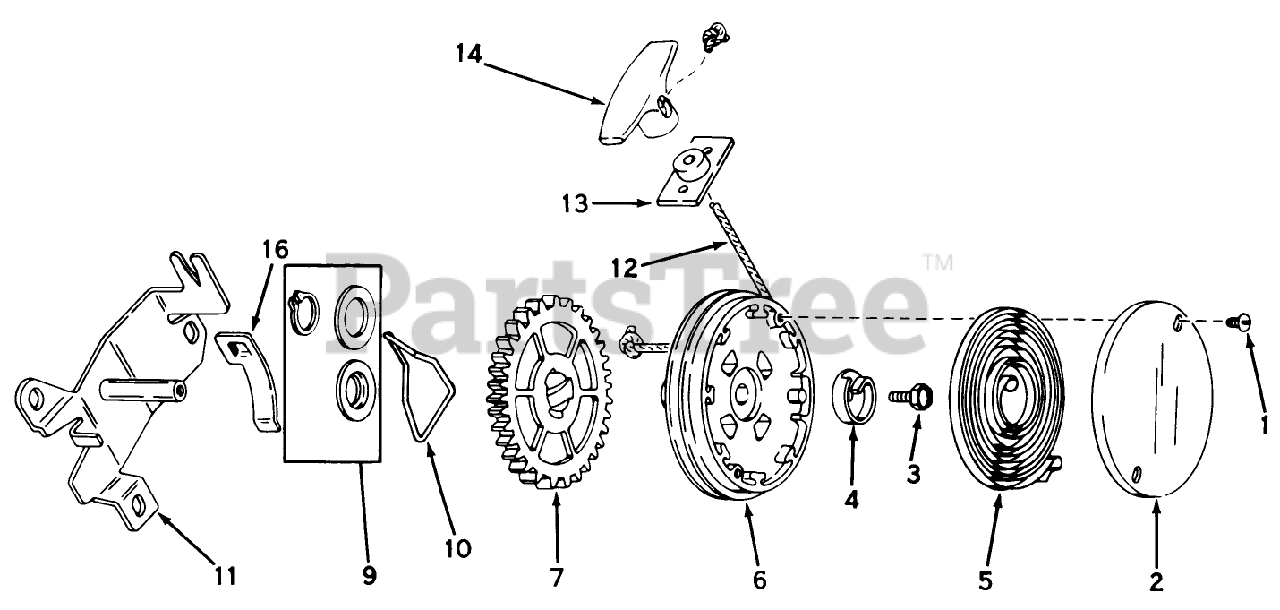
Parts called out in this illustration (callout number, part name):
1	Screw
2	Cover, Spring
3	Screw, Hex Washer Head
4	Hub Spring
5	Spring, Rewind
6	Pulley Assy. (Incl. No. 9)
9	Kit, Thrust Wash. Snap Rg.
10	Brake
11	Bracket Assy. Mounting
12	Rope-Starter
13	Bracket Assy.
14	Handle-Starter
16	Clip Rope
